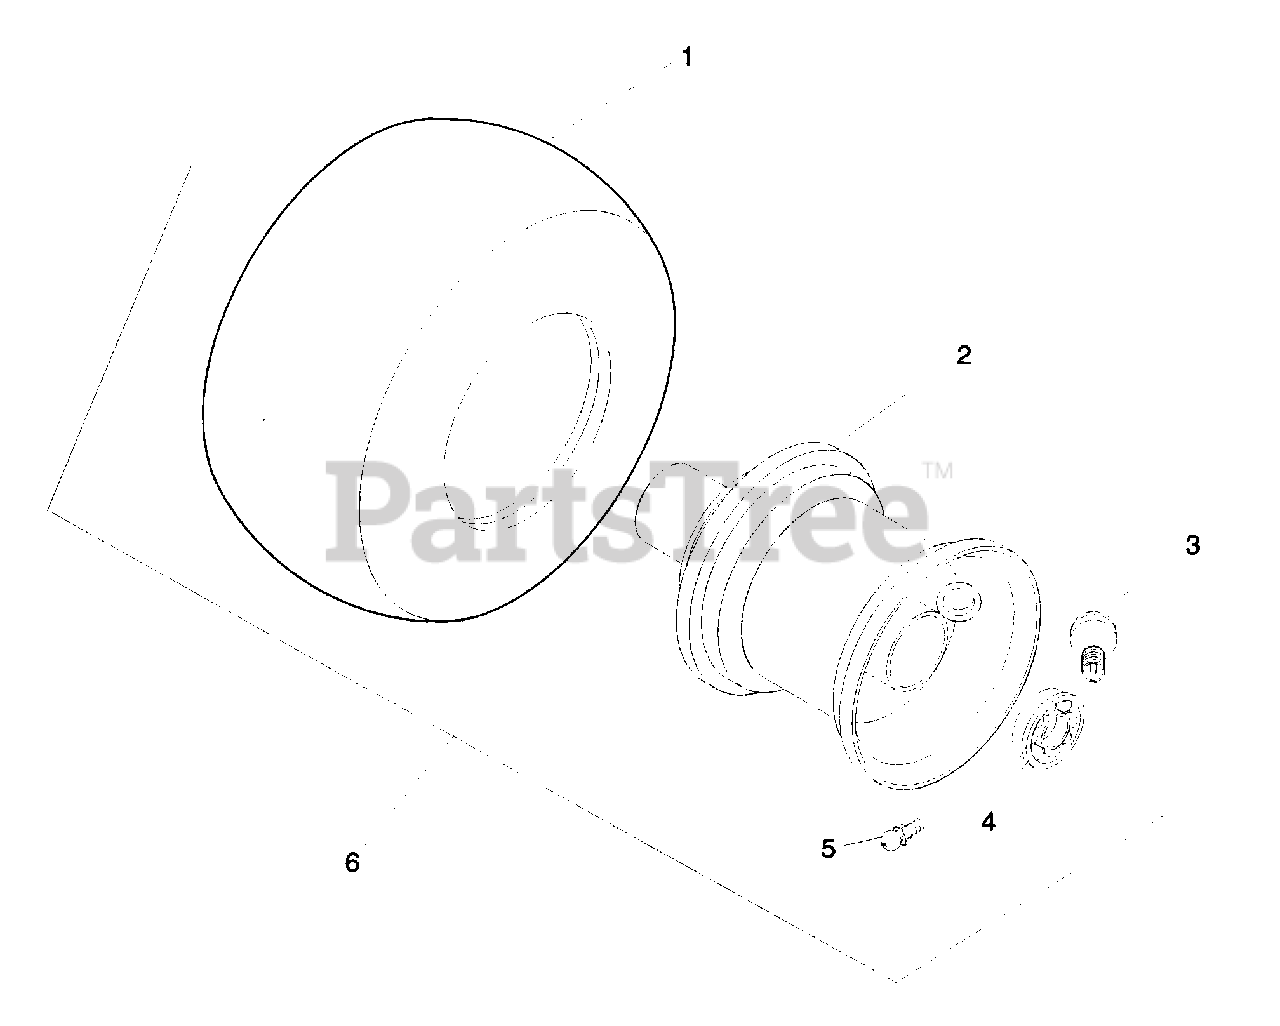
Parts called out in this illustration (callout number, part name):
1	Tire, 13 x 6.5-6
2	Rim-Assembly
3	Valve Stem Assembly
4	Radial Bearing
5	Fitting-Lube .25-28 x .256
6	Assembly, Wheel, 13 x 6.50-6
